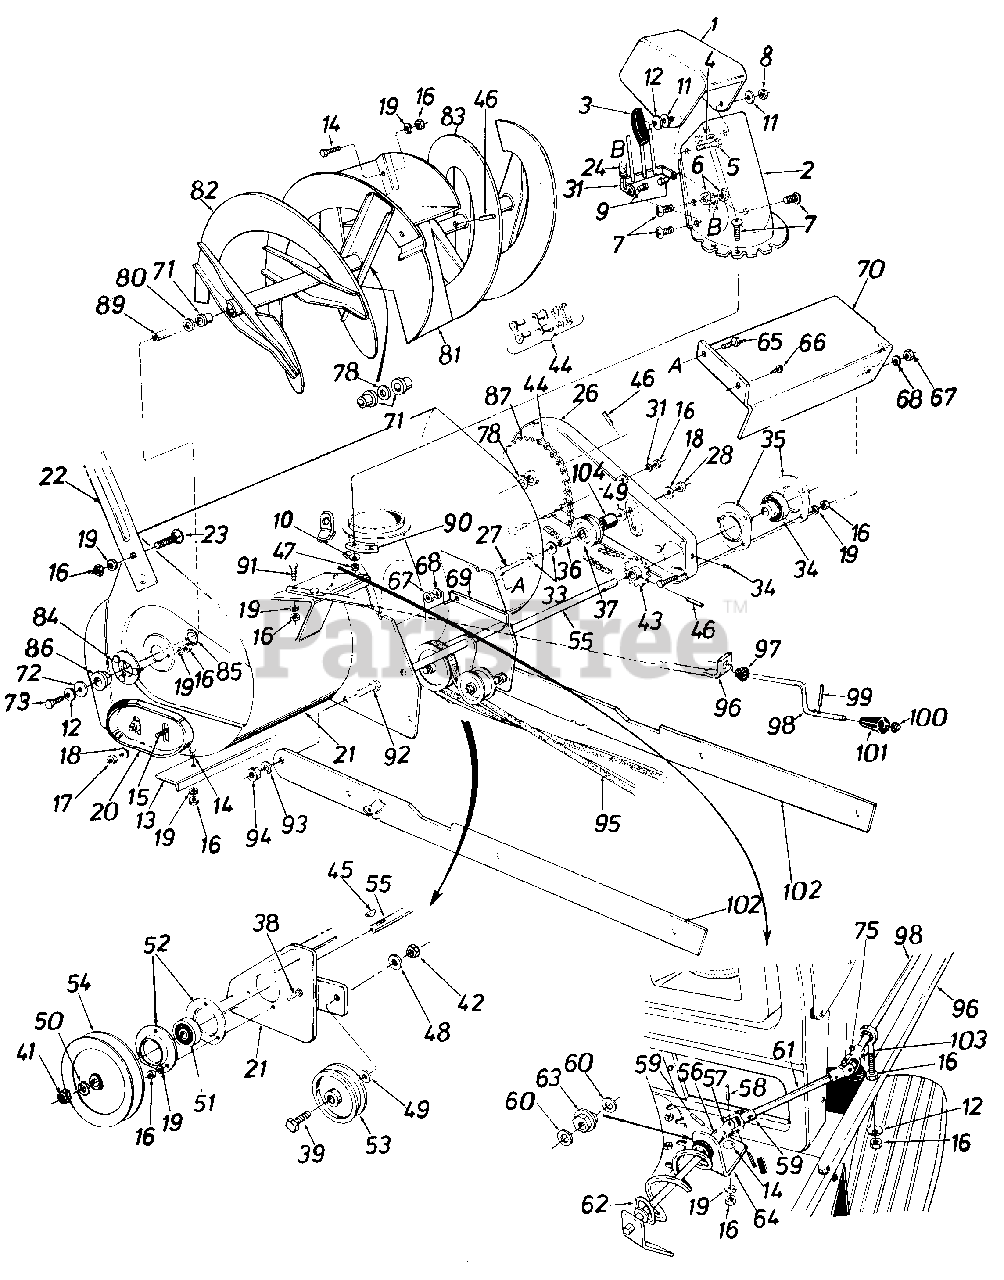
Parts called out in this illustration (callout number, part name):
1	Upper Chute
2	Lower Chute
3	Knob Handle Ass'y.
4	Truss Mach. Scr. 5/16-18 x .75" Lg.
5	Carriage Bolt 5/16-18 x 1.0"*
6	Hex Cent. L-Nut 5/16-18 Thd.
7	Truss Mach. Scr. 1/4-20 x .75" Lg.
8	Hex Cent. L-Nut 5/16-18 Thd.
9	Shld. Nut 1/4-20 Thd.
10	Fl. Wash. 1/4" I.D.
11	Fl.-Wash. .344" I.D. x 1.125"
12	Bell. Wash. .345" I.D. x .88"
14	Carriage Bolt 5/16-18 x .62"
15	Carriage Bolt 3/8-16 x .62"*
16	Hex Nut 5/16-18 Thd.*
17	Hex Jam Nut 3/8-16 Thd.
18	Bell. Wash. .40 I.D. x .88"
19	L.-Wash. 5/16" I.D.*
20	Slide Shoe
21	Spiral Hsg. Ass'y.-36"
22	Guide Blade
23	Carriage Bolt 5/16-18 x .62"*
24	Extension Spring
26	Chain Guard Ass'y.
27	Hex Bolt 3/8-16 x 2.00 4.*
28	Hex Inst.-Nut 3/8-16 Thd.
33	Fl.-Wash. .385" I.D. x .87" O.D.
34	Ball Brg. .75" I.D.
35	Flangette
36	Spacer .375" I.D. x .60" O.D.
37	Fl.-ldler w/Flanges 1.875
38	Hex Sems Bolt 5/18x.75" 4.
39	Hex Bolt 3/8-16 x 1.75" 4.*
41	Hex Jam Nut 3/4-10 Thd.
42	Hex Jam Nut 3/8-16 Thd.
43	Sprocket Ass'y.-14 Teeth
44	#420 Chain x 1/2" Pitch- 0 77 Links
45	#61 Hi-Pro-Key 3/16 x 5/8"
46	Spring Pin Spir. 5/16" Dia. x 1.75" Lg.
47	Hex L-Nut 1/4-20 Thd.
48	L.-Wash. 3/8" I.D.*
49	Fl.-Wash. .406" I.D. x 1.25"
50	Spring L.-Wash. 3/4" I.D.
51	Self-Aligning Brg.
52	Flangette
53	Idler Pulley
54	5/8 V Pulley .75" I.D. x 6"
55	Drive Shaft Ass'y
56	Joint Brkt. Ass'y.
58	Oval Head Rivet
59	Spiral Pin 1/8" Dia.
60	Fl.-Wash. .385" I.D. x .62"
61	Chute Crank Ext. Rod
62	Chute Crank Ass'y. R.H.
63	Plastic Bushing .380" I.D.
64	Chute Crank Brkt.
65	Hex Bolt 1/4-20 x .62" Lg.*
66	Hex Wash. S-Tap Scr. 1/4-20 0 x .50" Lg.
67	Hex Nut 1/4-20 Thd.*
68	L.-Wash. 1/4" I.D.
70	Drive Shaft Cover
71	Plastic Bushing
72	Washer .39" I.D. x 1.75" O.D
73	Hex Bolt 5/16-18 x .88" Spec
75	Cotter Pin 3/32" Dia.
78	Fl.-Wash. 1.03" I.D. x 1.62"
80	Fl.-Wash. 1.0" x 1.75"
85	Snap Ring for 1.50" Shaft
86	Flange Brg. w/flats 1.00" I.D.
87	Sprocket Hub Ass.y. 40 Teet
90	Chute Flange Keeper
91	Hex Bolt 5/16-18 x 1.5" Lg.*
92	Hex Bolt 1/2-13 x 1.25" 4.*
93	L.-Wash. 1/2" I.D.*
94	Hex Nut 1/2"13 Thd.*
95	"V"Belt
98	Chute Crank 34.5" L.g
99	Roll Pin .12 Dia. x .63
100	Push Nut 3/8" Rod
101	Knob Black
102	Linkage Arm
103	Eye Bolt 5/16-18 x 3.0" 4.
104	Idler Spacer
